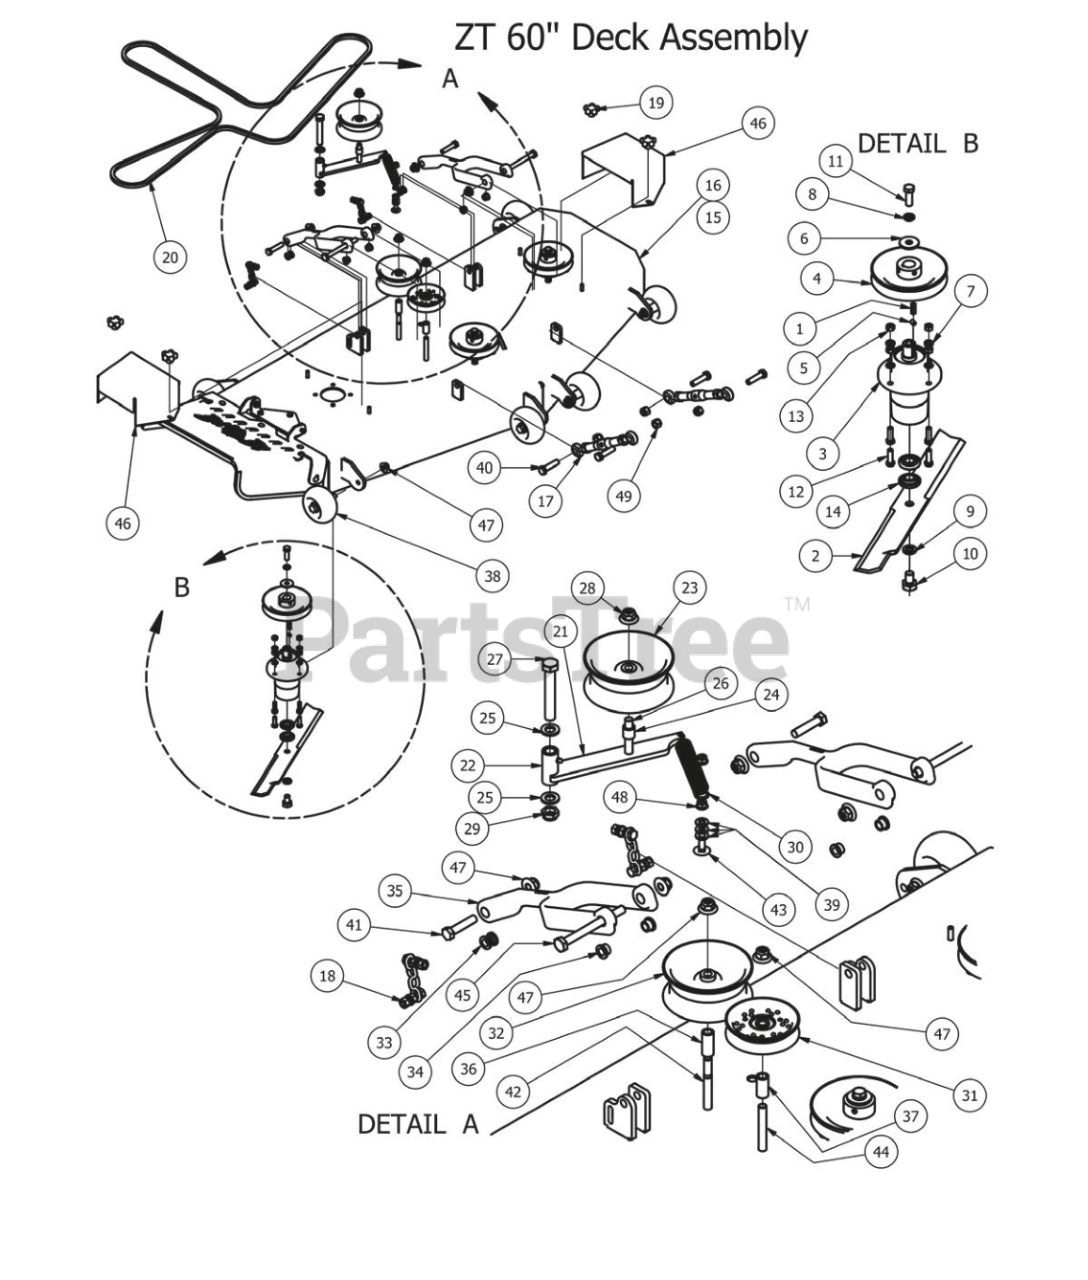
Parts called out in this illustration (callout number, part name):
1	1/4" x 1" Key
2	60 Inch Fusion Blade
3	Spindle - Aluminum - 2012 ZT
4	6 1/4" Drive Pulley
5	5/16 Set Screw
6	1/2 Belleville Washer
7	3/8" Lock Washer
8	1/2" Lock Washer
9	5/8" Lock Washer
10	5/8" x 1 1/2" Grade 8 Bolt
11	1/2"-20 x 1 1/2 - Grade 5 Fine Thread Bolt
12	3/8" x 1 1/4" Hex Bolt
13	3/8" Hex Nut
14	Spindle Bearing
15	60" ZT Deck Complete Assembly
16	60" ZT Deck Only
17	Turnbuckle (Top Link)
18	Chain assembly
19	5/16" Knob
20	60" ZT Deck Belt
21	Deck Idler Assembly components 22,23,24,26,28
22	Deck Idler Bracket
23	5 3/4" Deck Idler Pulley
24	3/4 OD x 1/2 ID x 3\4 Length
25	.635 ID Plastic Washer
26	1/2-13 x GR 5 Hex Bolt Zinc
27	5/8" x 4" Hex Bolt
28	1/2-13 Nylon Flange Nut-Orange
29	5/8" Nylock (1/2 Jam)
30	60" Deck only Deck Idler Spring
31	4-3/4 Idler Pulley
32	5 3/4" Deck Idler Pulley
33	Flange for Lower Deck Arm
34	Flange Bushing For Deck Arm upper
35	Deck Arm Assembly
36	1 3/4" Pulley Spacer
37	Pup Pulley Spacer
38	Deck Wheel
39	3/8" Flat Washer
40	5/8" x 2 1/2" Hex Bolt
41	1/2-13X 2-1/4 GR Hex Bolts
42	1/2" x 4" Bolt (Grade 8)
43	3/8 x 1-1/2 Carriage Bolt
44	1/2 x 3 1/2 Flange Bolt Grade 8
45	1/2" x 5 1/2" Bolt
46	Pulley Cover
47	1/2-13 Nylon Flange Nut-Orange
48	3/8" Nylock Flange Nut
49	5/8 Std NC Nylock Nut
